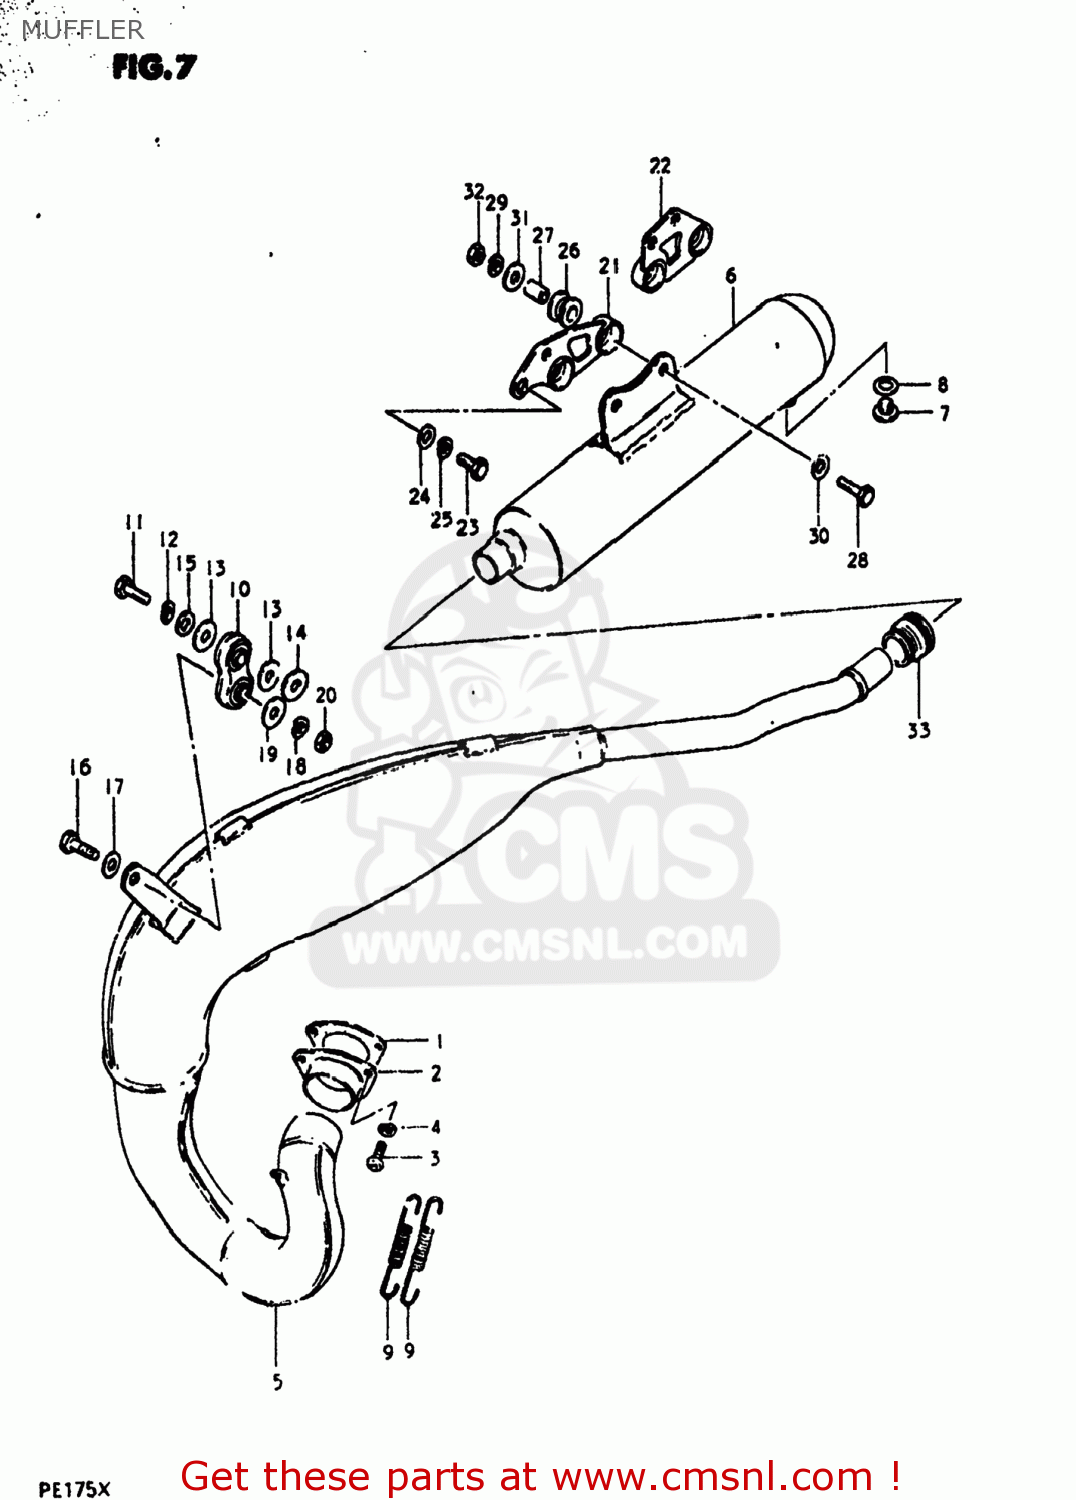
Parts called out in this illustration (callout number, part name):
1	GASKET,EXHAUST PIPE (MCA)
2	FLANGE,EXHAUST PIPE
3	SCREW
4	LOCK WASHER
5	BODY,MUFFLER
6	MUFFLER ASSEMBLY
7	PLUG(12X9)
8	GASKET(12X16X2) (NAS)
9	SPRING
10	DAMPER,MUFFLER
11	BOLT
12	LOCK WASHER
13	WASHER
14	SPACER(8.4X12X12)
15	WASHER
16	BOLT
17	WASHER
18	LOCK WASHER
19	WASHER
20	NUT
21	DAMPER,MUFFLER SUPPORT
22	DAMPER,MUFFLER SUPPORT
23	BOLT
24	WASHER
25	LOCK WASHER
26	CUSHION
27	SPACER (8.2X12X17)
28	BOLT
29	LOCK WASHER
30	WASHER
31	WASHER (8.5X29X1.6)
32	NUT
33	CONNECTOR,MUFFLER
